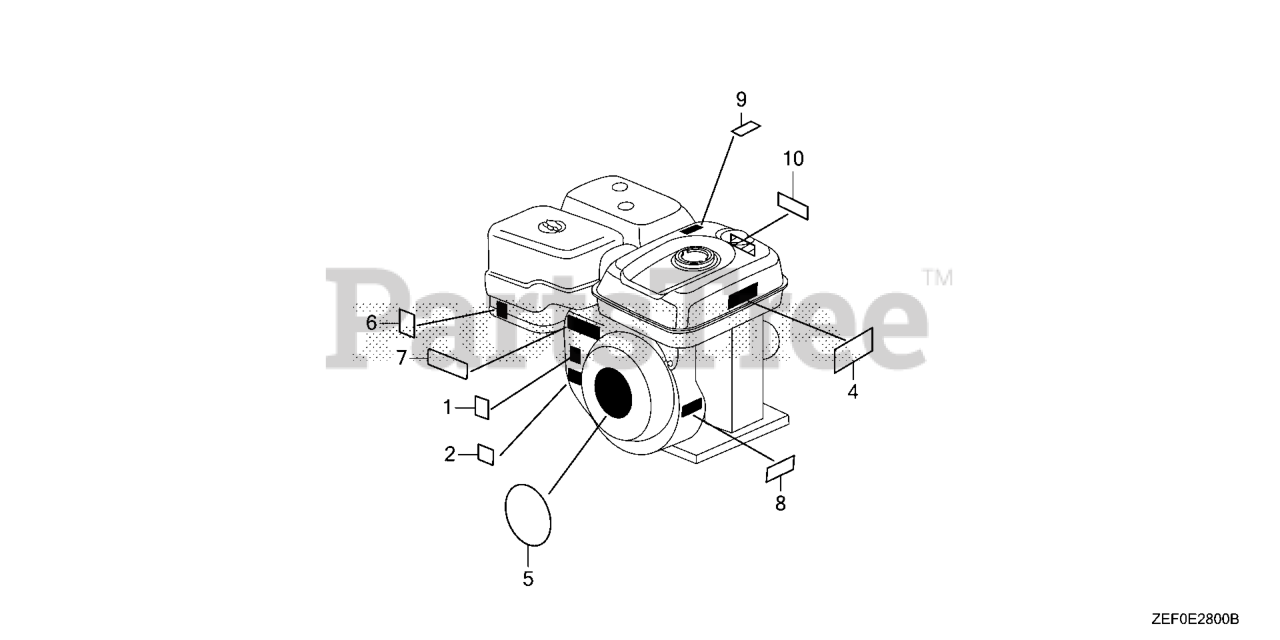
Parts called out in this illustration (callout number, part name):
2	LABEL, WARNING (NOT CERTIFIED FOR SALE)
4	MARK, OPERATOR CAUTION
5	EMBLEM (GX200)
6	MARK, CHOKE
7	MARK, THROTTLE INDICATION
9	MARK, EX. CAUTION (ENGLISH)
